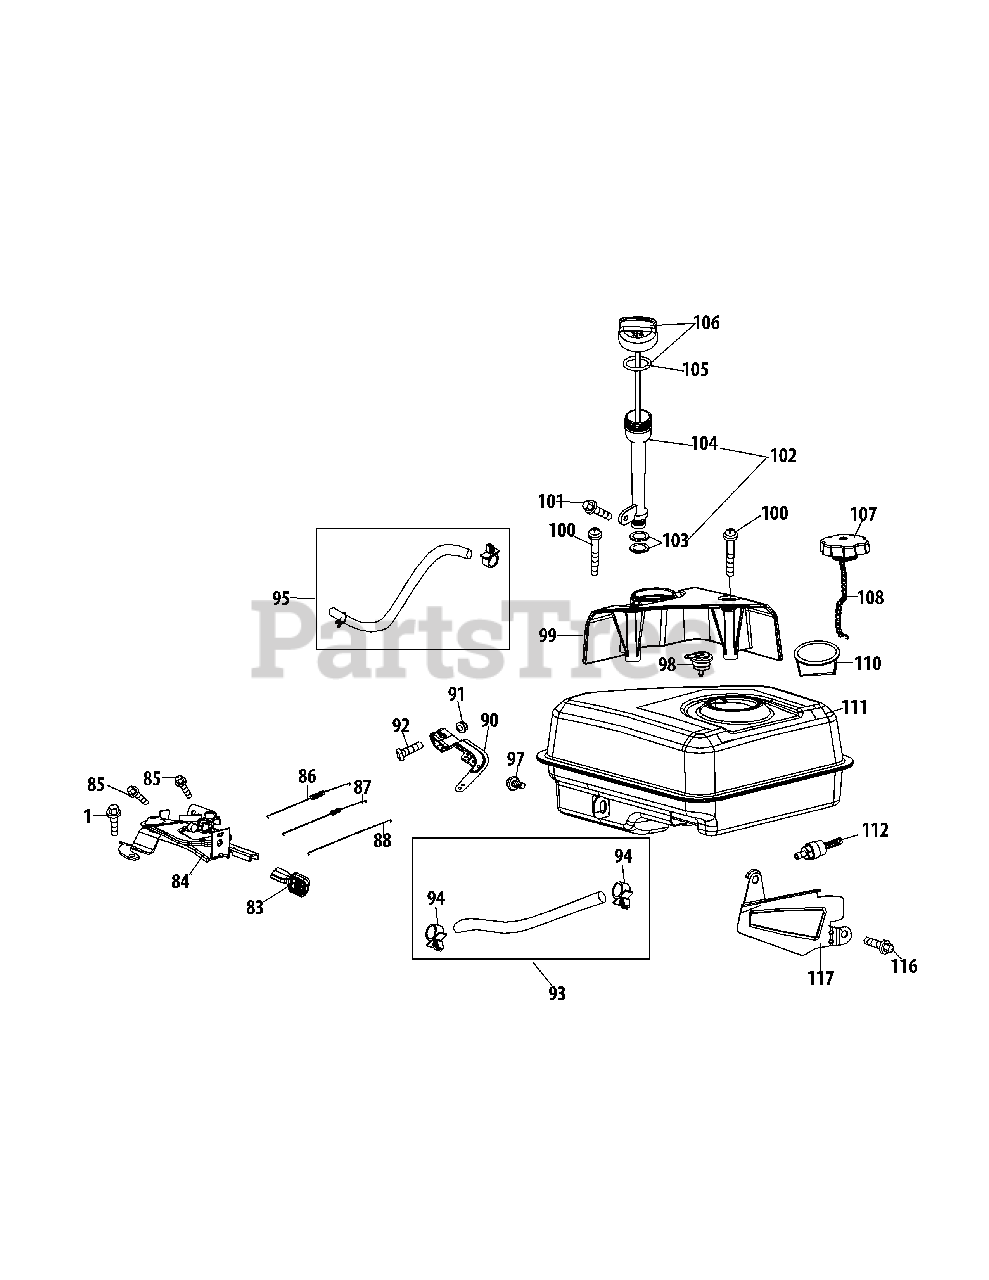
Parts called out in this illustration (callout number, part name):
1	Bolt M6×16
83	Throttle Control Knob
84	Primer Bracket
85	Bolt M6×12
86	Governor Spring
87	Throttle Linkage Spring
88	Throttle Linkage
90	Governor Arm
91	Nut M6
92	Governor Arm Bolt
93	Fuel Line Kit
94	Fuel Hose Clamp
95	Evap Hose Assembly
97	Bolt M6×12
98	Roll Over Valve
99	Engine Dipstick Cover
101	Bolt M6×12
102	Oil Fill Tube Assembly
103	Fill Tube O-Ring
104	Dipstick Tube
105	Dipstick O-Ring
106	Dipstick Assy
107	Fuel Cap Assembly
108	Fuel Cap Chain
110	Fuel Level Indicator
111	Fuel Tank
112	Fuel Tank Nipple
116	Bolt M6×10
117	Air Flow Shield
